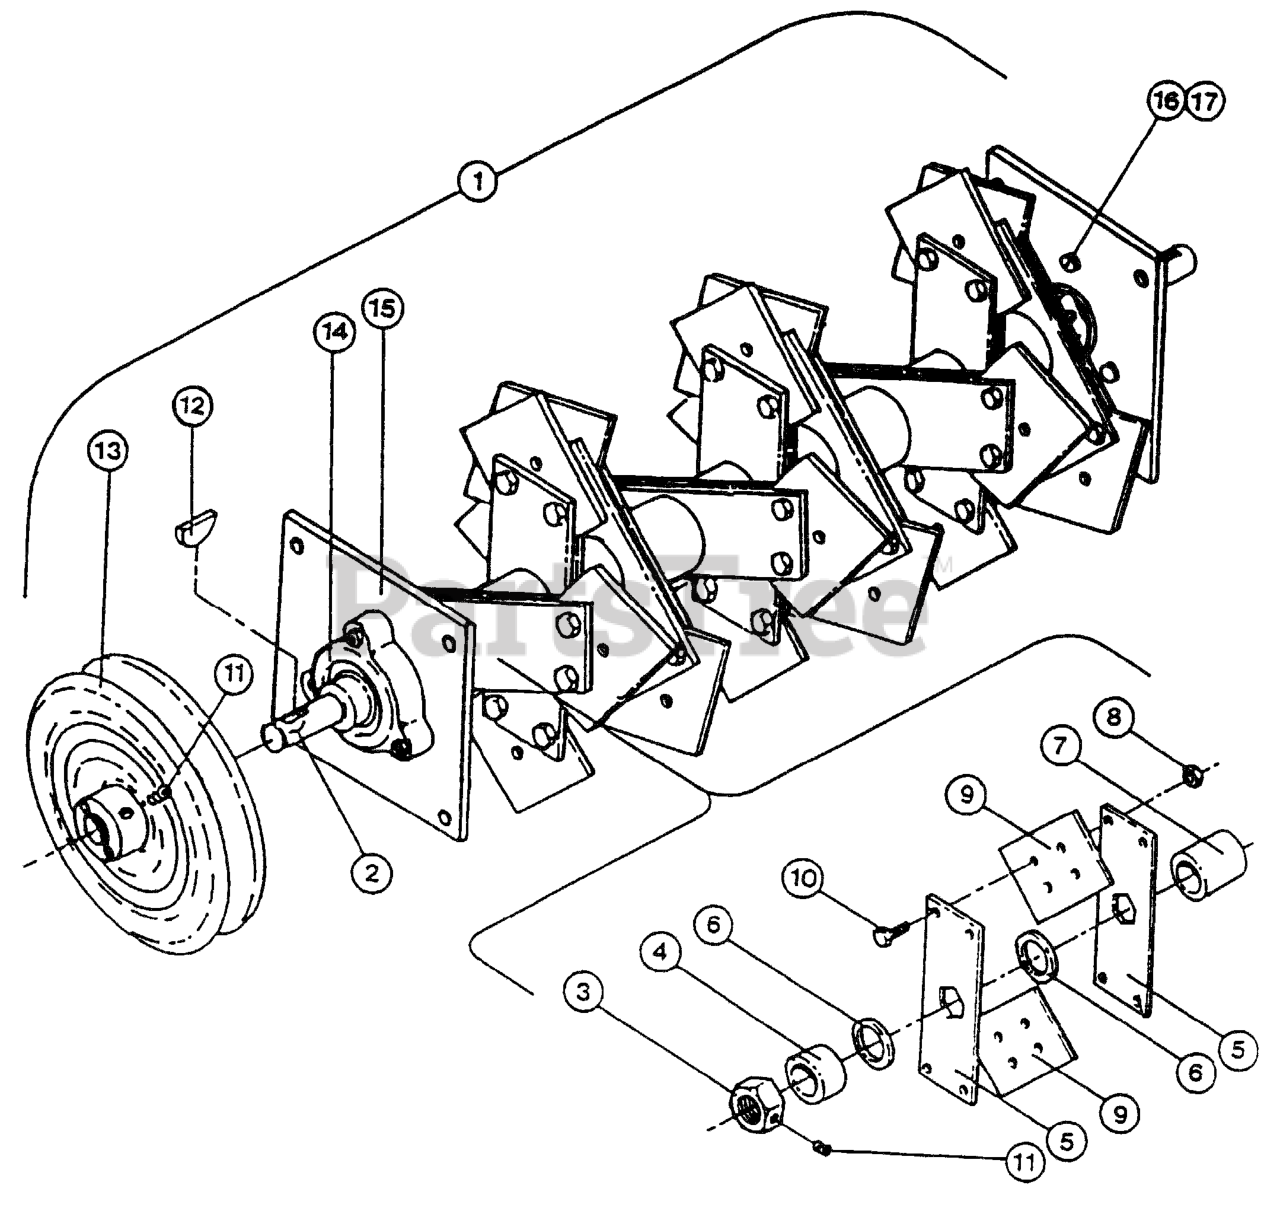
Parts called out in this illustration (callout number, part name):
1	KIT-SLICER SHAFT QUICK CHANGE
2	SLICER SHAFT, BARE
3	JAM NUT W/SET SCREW
4	SPACER, SLEEVE SHORT
5	BLADE HOLDER PLATE
6	WASHER, BLADE
7	SPACER, SLEEVE (LONG)
8	NUT.1/4-20.HEX.NYLOC.ZD
9	SLICER BLADE
10	HCS 1/4C X 5/8
11	SET SCREW 5/16 NYLOC
12	KEY, #9 WOODRUFF
13	PULLEY, MAIN SHAFT
14	BEARING, FLANGED
16	BOLT, TAP 5/16-18
17	NUT 5/16 NYLOC
